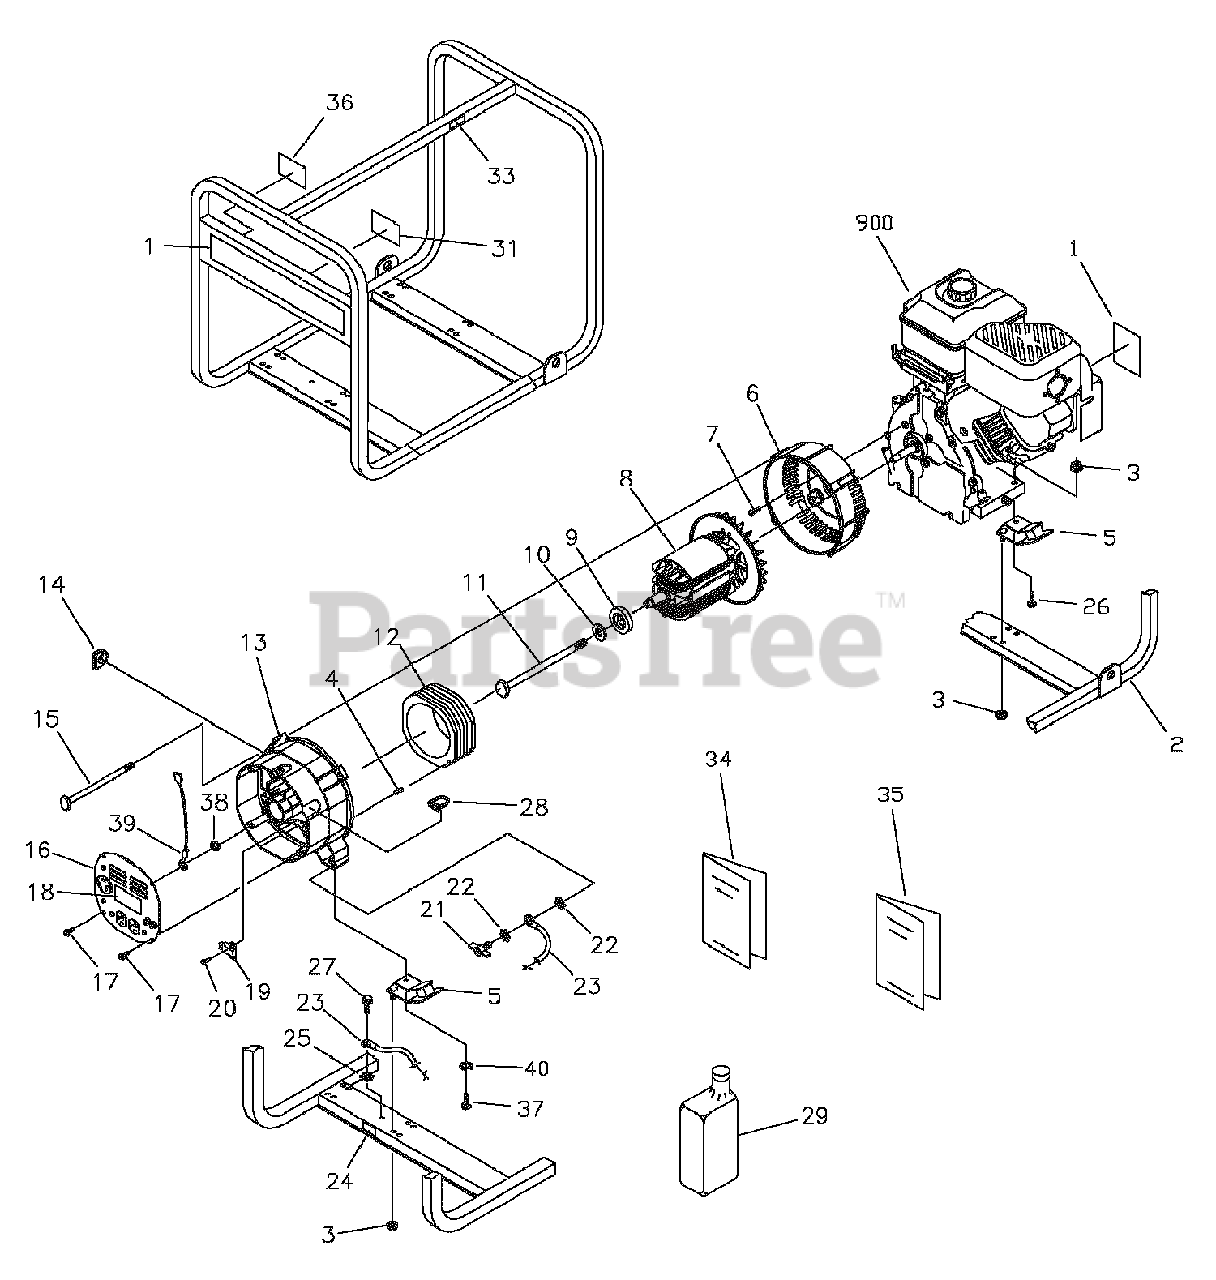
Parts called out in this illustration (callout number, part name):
1	SET, Decal, Unit & Air Cover
2	ASSY, Cradle
4	PIN, Roll
5	MOUNT, Vibe
6	HOUSING, Engine Adapter
8	ASSY, Rotor (Includes Item 9)
9	BEARING, Ball
12	ASSY, Stator
13	CARRIER, Rear Bearing
14	GROMMET, Rubber
16	ASSY, Control Pan (see page 18)
18	DECAL, Control Panel
19	RECTIFIER, Brush & Bridge
20	SCREW
21	SCREW, Wing
22	WASHER, Ext. M6 - 1/4" Shakeproof
23	WIRE, Ground
24	DECAL, Ground
26	SCREW
27	SCREW
28	GROMMET, Plastic RBC
29	BOTTLE, Oil
31	DECAL, Start Instructions
33	DECAL, Caution Hot Muffler
34	MANUAL, Owners
35	MANUAL, Engine
36	DECAL, Danger
39	WIRE, Ground, Panel
40	WASHER, Lock
900	* ENGINE, NSP
